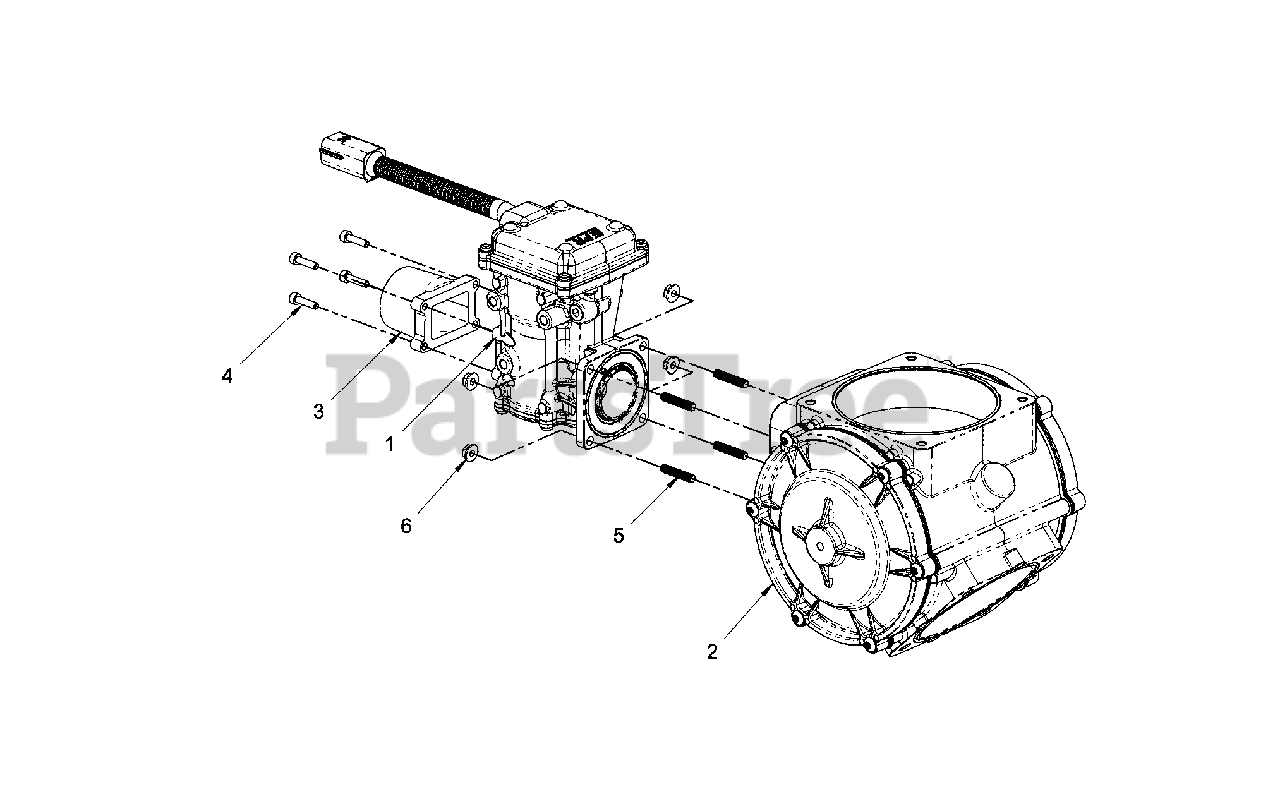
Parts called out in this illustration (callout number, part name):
1	EPR
2	MIXER
3	ADAPTER
4	* BOLT
5	* STUD
6	* NUT
